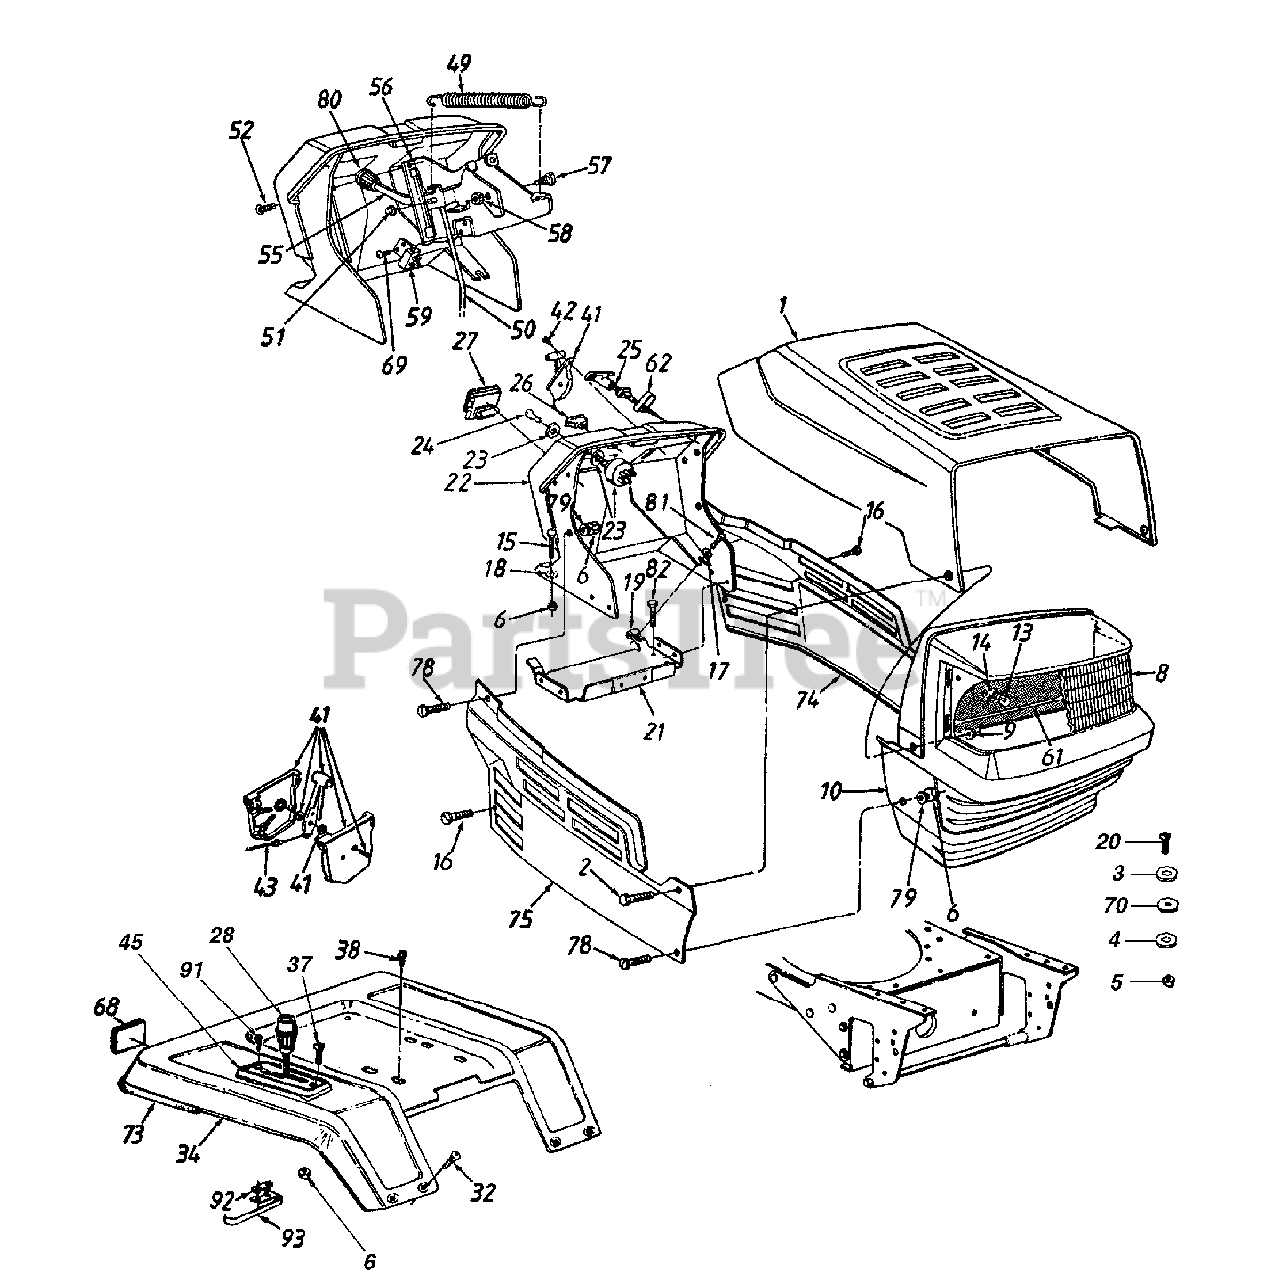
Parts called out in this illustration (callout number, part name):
3	Fl-Wash. .34" I.D. x 1" O.D.
4	L-Wash. 5/16" I.D.
5	Hex Nut 5/16-18 Thd. (Gr. 5)
6	Hex Sems Nut 1/4-20 Thd.
8	Headlight Lens w/Logo
9	Flange L-Nut 1/4-20 Thd.
10	Grille
13	Lamp
14	Socket
15	Carriage Bolt 1/4-20 x 1.0" Lg.
16	Hx Wash Hd. TT-Tap Scr. 1/4-20 x .5"
17	Fl-Wash. .281" I.D. x .73" O.D.
18	Bolt Retainer 1/4" I.D.
19	Speed Nut 1/4-20 Thd.
20	Hex Bolt 5/16-18 x .75" Lg.
23	Ignition Switch
24	Ignition Key
25	Choke Control
27	Ammeter (Optional)
28	Shift Knob
32	Carriage Bolt 1/4-20 x .5" Lg.
38	Hx Wash Hd. AB-Tap Scr. 5/16 x .75"
41	Throttle Box Ass'y.
42	Truss Mach. AB-Tap Scr. #10 x .5" Lg.
43	Throttle Control Wire 35" Lg.
45	Selector Plate
49	Ext. Spring 5.06" Lg.
50	Deck Control Rod
51	Speed Nut 1/4" Rod
52	Torx Mach. Scr. 1/4 x .62" Lg.
55	PTO Lever
58	Hex L-Nut 5/16-18 Thd.
59	Safety Switch
61	Grille Reflector Label
62	Retainer Clip
68	Reflector (Optional)
69	Hx Wash. Hd. B-Tap Scr. #10 x .38" Lg.
70	U-Nut 5/16-18 Thd.
73	Trim Strip 81" Lg.
79	Bell-Wash. 1/4" I.D.
81	Hex TT-Tap Scr. 1/4-20 x .75" Lg.
82	Hex AB-Tap Scr. 1/4 x .62" Lg.
91	Hex Wash. Hd. AB-Tap Scr.
92	Insulator Nut Plate
93	Reverse Safety Switch
